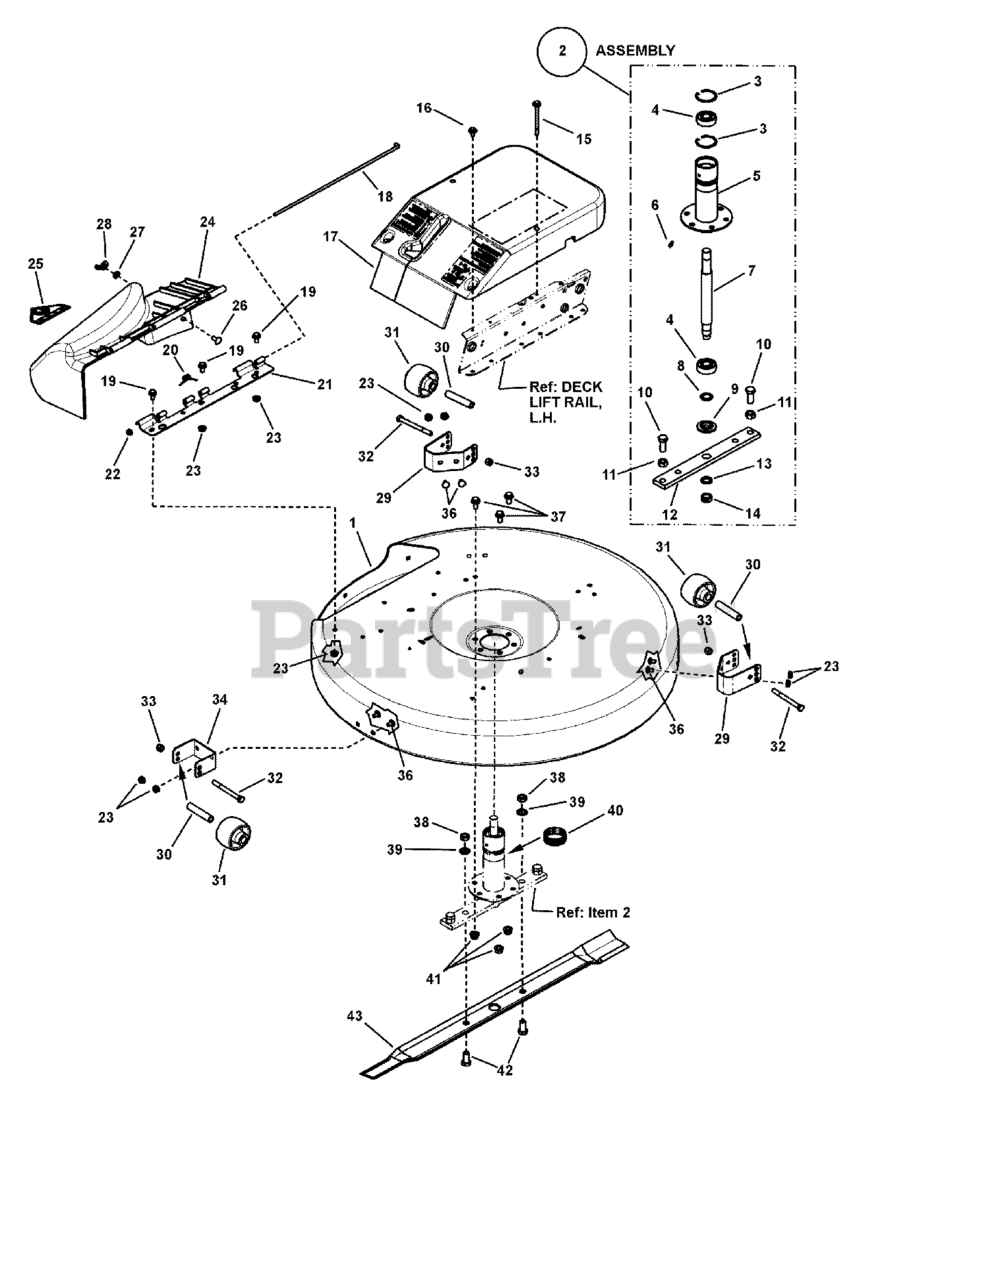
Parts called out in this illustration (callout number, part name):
1	DECK, 28" Replacement (painted deck w/decals)
2	ASSEMBLY, Spindle Housing
3	RING, 1.85" Internal Retaining
4	BEARING, Spindle
5	ASSEMBLY, Housing
6	LUBE FITTING, 3/16" Press-In
7	SPINDLE, Rider (10.327" overall length)
8	WASHER, .77 x 1.13 x .06 Flat
9	WASHER, Spindle
10	SCREW, 1/2-20 x 1-1/4" Hex Head Cap, GR 5
11	NUT, 1/2-20 Hex, GR 5 or B
12	HOLDER, Blade (for 28" Deck)
13	SPACER, Blade Centering
14	NUT, 5/8-18 Hex Center Lock Jam
15	SCREW, 1/4-20 x 3-1/2" Hex Head w/Free Spinning Washer
16	SCREW, 1/4-20 x 5/8" Hex Head w/Free Spinning Washer
17	COVER, Spindle
18	PIN, Hinge
19	BOLT, 5/16-18 x 5/8" Hex Flange Lock, GR 5
20	SPRING, Hinge
21	HINGE, Deflector (Deck side)
22	PUSH NUT, 1/4"
23	NUT, 5/16-18 Hex Flange Lock, GR 5
24	ASSEMBLY, Discharge Deflector 28" (w/o decal)
24	DEFLECTOR, Discharge, 28"
25	DECAL, Danger, (Cut Finger) International Symbol
26	BOLT, 5/16-18 x 3/4" Short Neck Carriage, GR 5
27	WASHER, 5/16" Flat
28	NUT, 5/16-18 Wing
29	BRACKET, Gage Wheel (Rear)
31	WHEEL, Gage
32	SCREW, 3/8-24 x 3-3/4" Hex Head Cap, GR 5
33	NUT, 3/8-24 Hex Nyloc
34	BRACKET, Gage Wheel (Front)
36	BOLT, 5/16-18 x 1/2" Short Neck Carriage, GR 5
37	BOLT, 3/8-16 x 3/4" Hex Flange Lock
38	NUT, 1/2-20 Hex Jam
39	WASHER, 1/2" Internal Tooth Lock
40	RING, Tolerance
41	NUT, 3/8-16 Hex Flange Lock
42	SCREW, 1/2-20 x 1" Hex Head Cap, GR 5
43	BLADE, Replacement Kit, 28"
